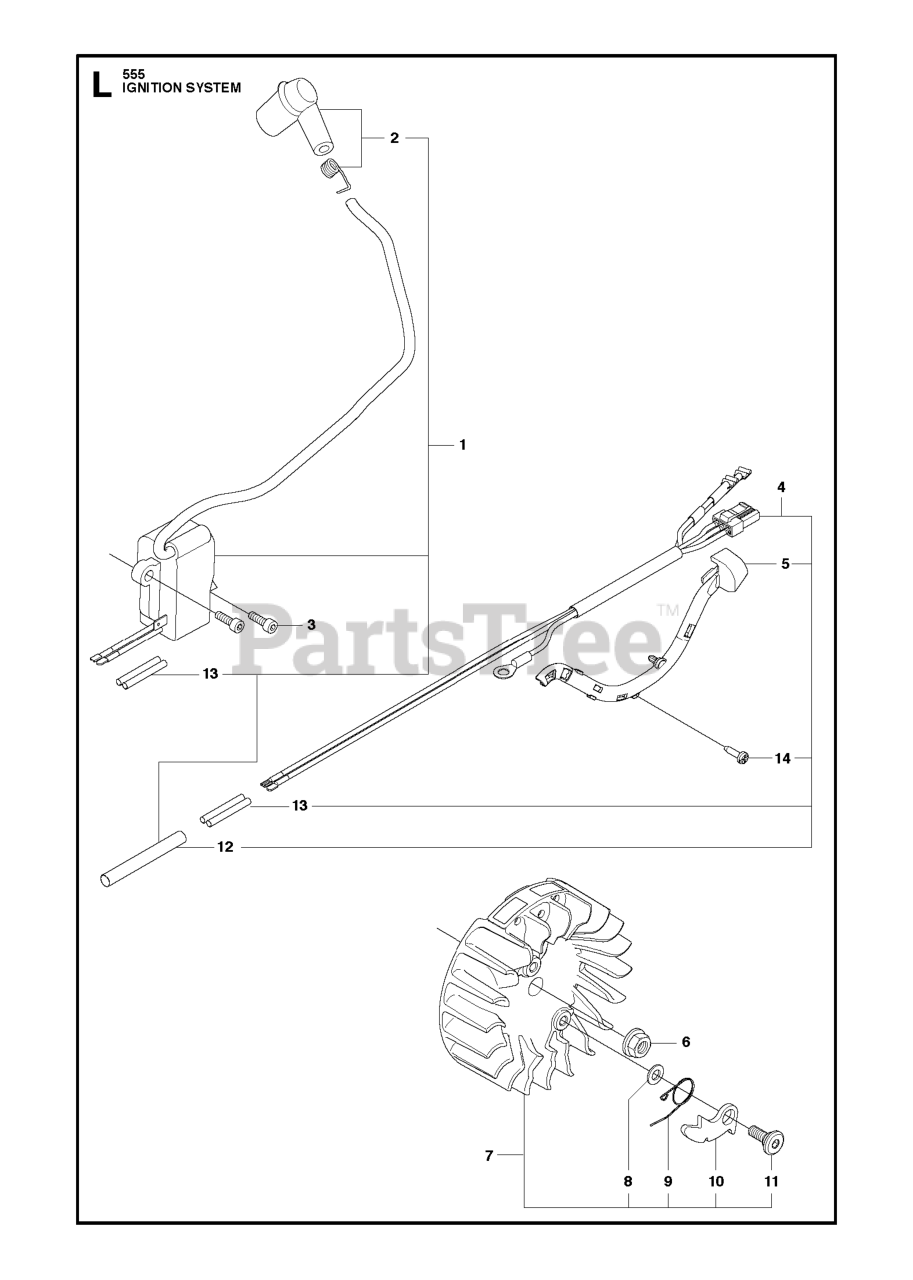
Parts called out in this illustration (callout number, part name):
1	IGNITION MODLUE ASSY
2	SPARK PLUG CAP ASSY
4	WIRING ASSY
5	CABLE HOLDER
6	NUT W/ WASHER
7	FLYWHEEL ASSY
8	WASHER
9	SPRING
10	PAWL
11	SCREW M5X14
12	CABLE COVER
13	SHRINK HOSE
14	SCREW
